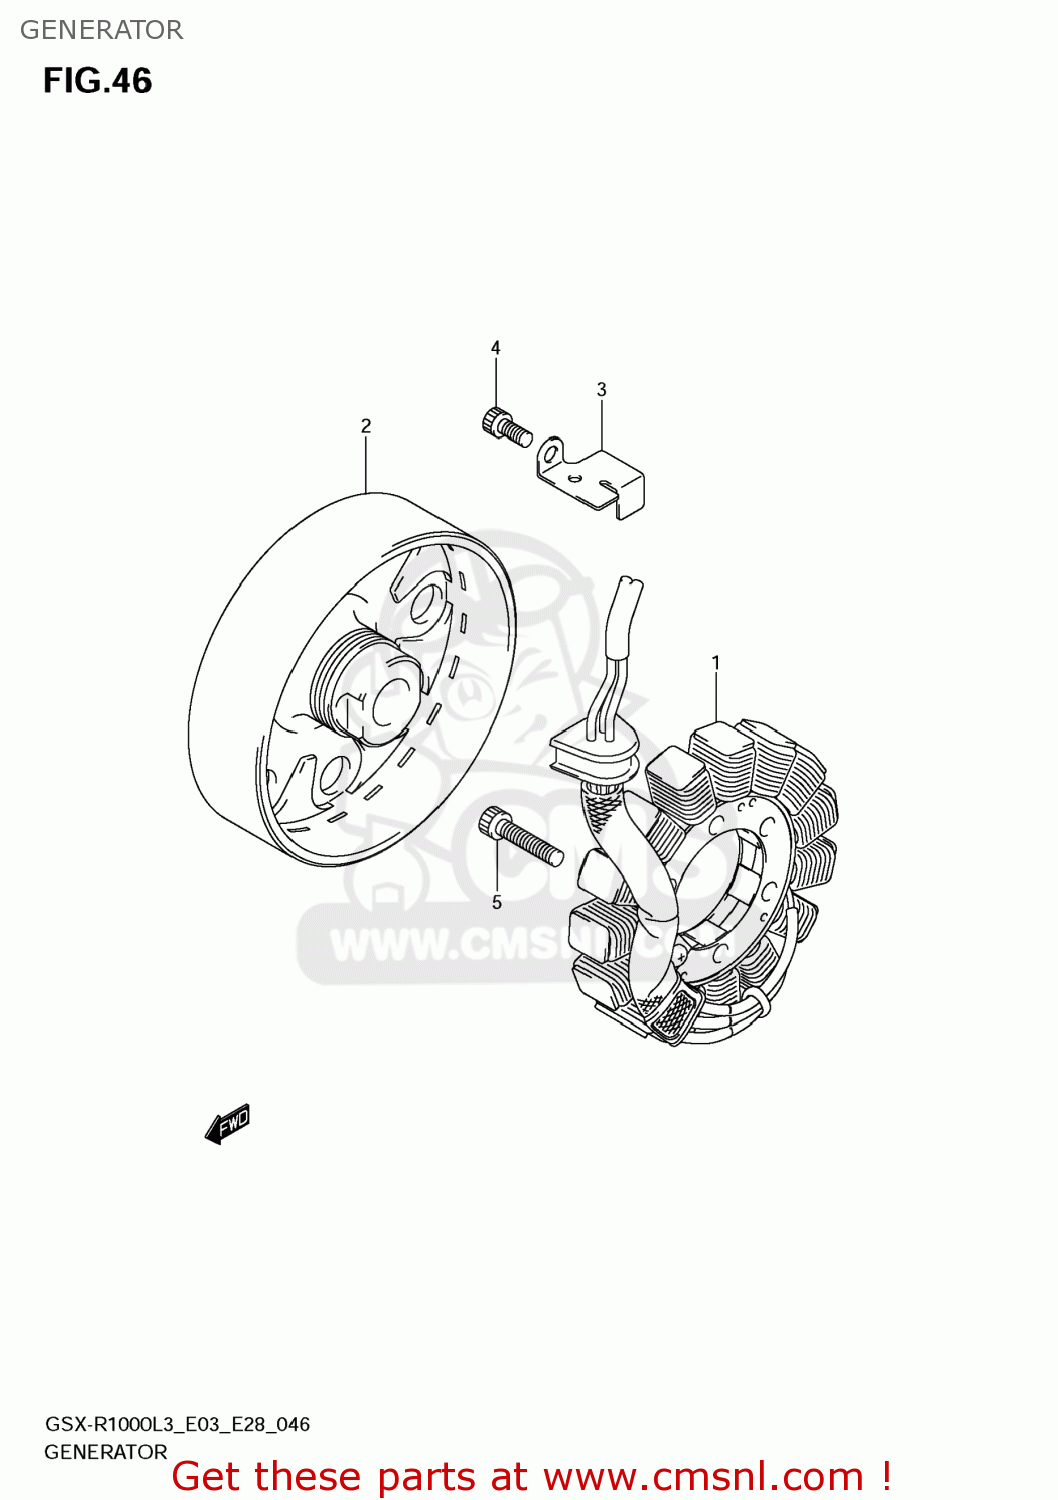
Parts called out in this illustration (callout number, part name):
1	STARTER ASSY
2	ROTOR ASSY
3	CLAMP,GENERATOR LEAD WIRE
4	BOLT
5	BOLT
